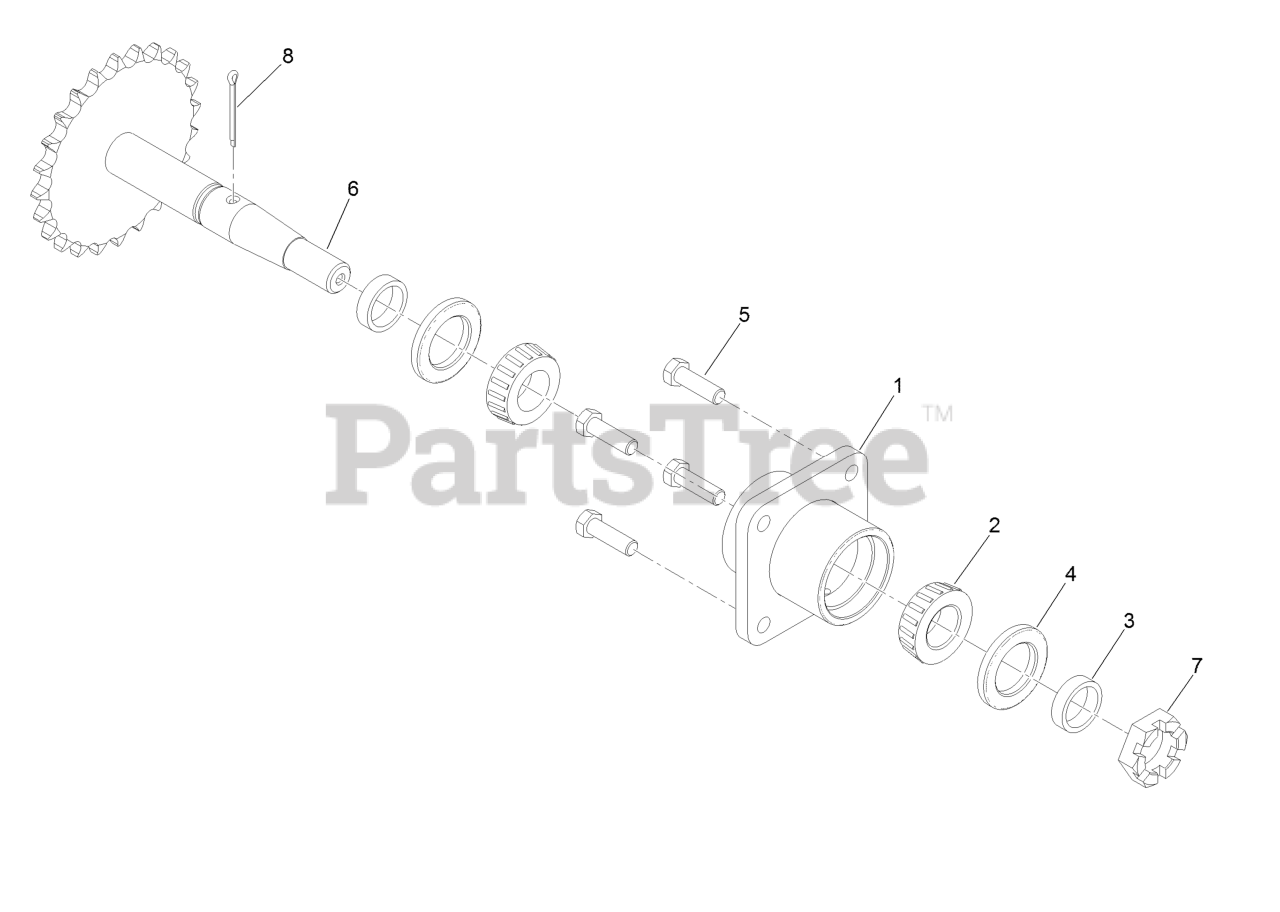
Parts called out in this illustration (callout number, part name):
1	Mount-Bearing, Wheel
2	Bearing-Roller, Tapered
4	Seal-Grease
5	Screw-HH
8	Pin-Cotter
